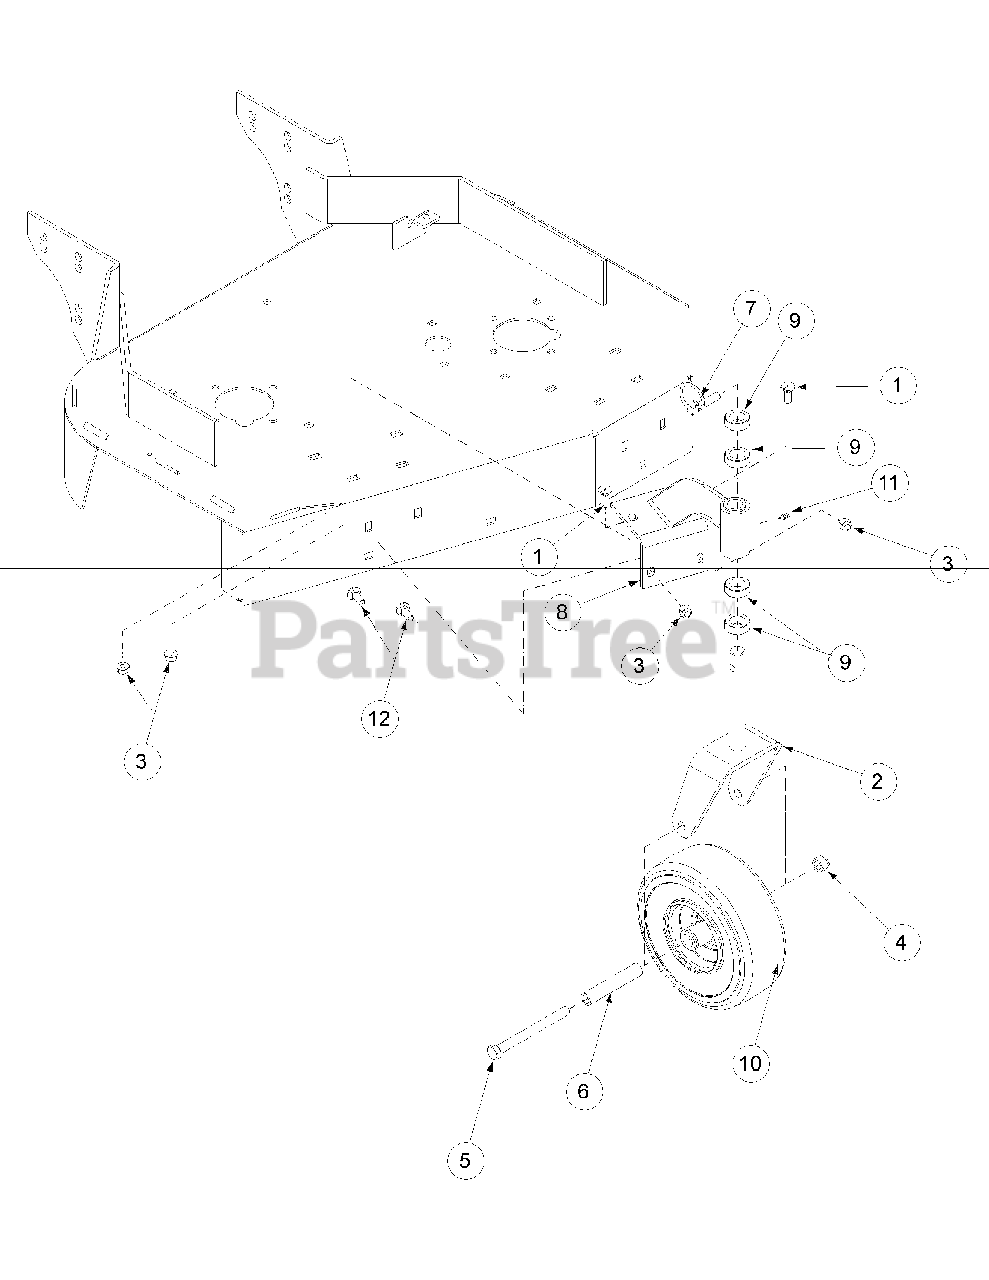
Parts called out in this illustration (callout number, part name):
1	Carriage Bolt, 3/8-16 x 1
2	Caster Yoke Assembly, Weldment
3	Nut, Hex Flange Lock, 3/8-16
4	Lock Nut, Nylon Insert, 1/2-13
5	Hex Cap Screw, 1/2-13, 5.50
6	Spacer Wheel
7	Klik Pin, 1.75
8	Caster Bracket Weldment
8	Caster Bushing
9	Spacer, Caster
10	Wheel Assembly, 9.0 x 3.50-4
11	Grease Fitting, 1/4-28 x 3/16
